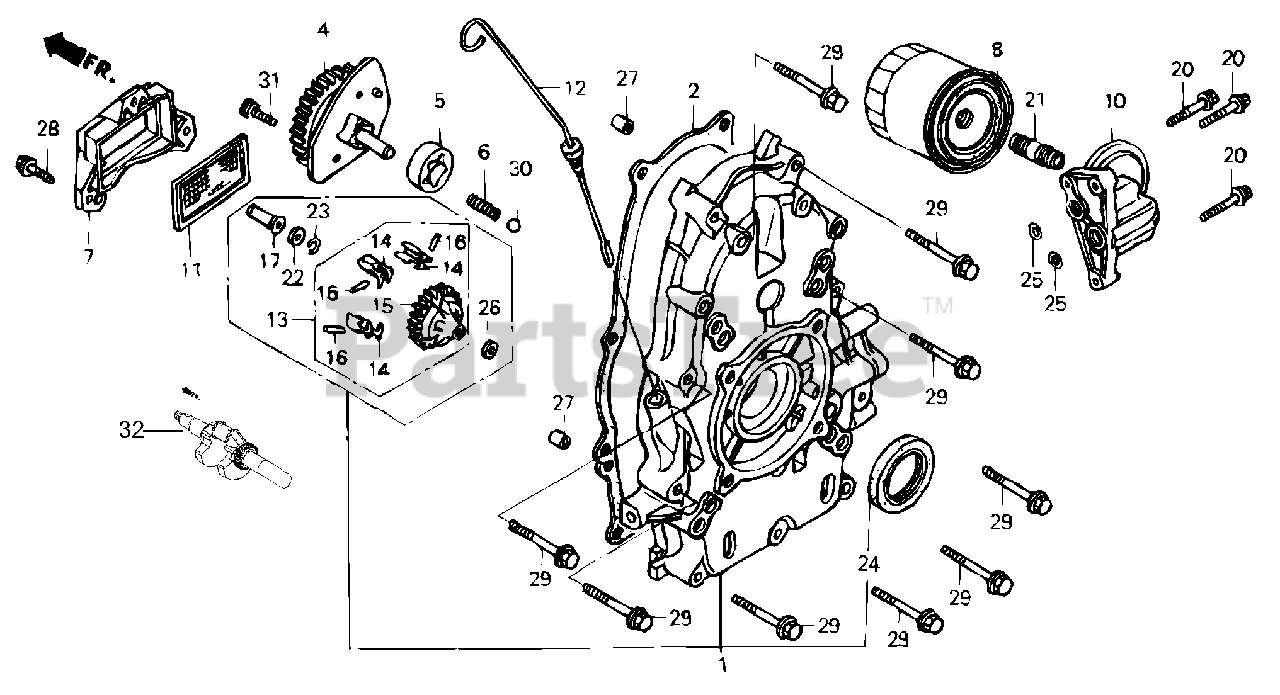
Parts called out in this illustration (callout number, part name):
1	Cover Assembly, Crankcase (Q-type)
2	Gasket, Case Cover
4	Cover Assembly, Oil Pump
5	Rotor, Oil Pump (Outer)
6	Spring, Relief Valve
7	Cover, Oil Filter
8	Filter, Oil
10	Base, Oil Filter
11	Screen, Oil Filter
12	Dipstick, Oil
13	Governor Assembly
14	Weight, Governor
15	Holder, Governor Weight
16	Pin, Governor Weight
17	Slider, Governor
20	Bolt, Flange (6x28)
21	Holder, Oil Filter
22	Washer (6x16)
23	Clip, Governor Holder
24	Oil Seal (38x58x9)
25	O-ring (11.8x2.4)
26	Washer, Plain (6mm)
27	Pin A, Dowel (8x14)
28	Bolt, Flange (6x20)
29	Bolt, Flange (8x50)
30	Ball, Steel (#12) (3/8)
31	Bolt, Socket (6x16)
32	Crankshaft
